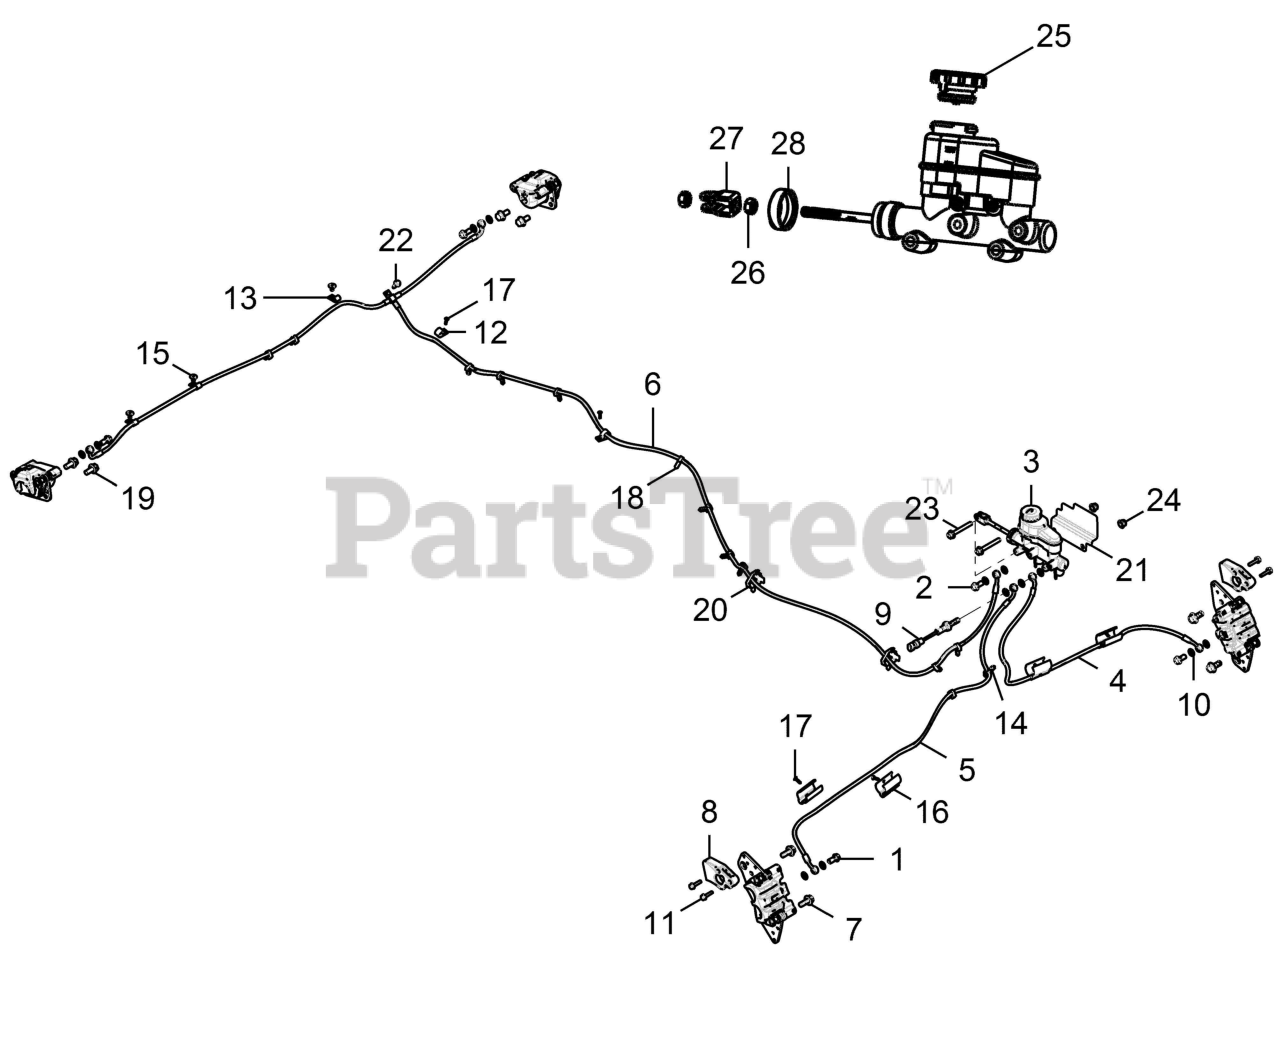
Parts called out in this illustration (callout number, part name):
1	BOLT-BANJO,10MMX1.00
2	BOLT-BANJO, 10MM X 1.25-6G
3	ASM-M/C-T,HBII,STD PUSH ROD
4	LINE-BRAKE,FRONT,LEFT,BRD
5	LINE-BRAKE,FRONT,RIGHT,BRD
6	LINE-BRK,3WAY,123",20B,90B,90B
7	BOLT-M10X1.25X25,HXFLG,W/PATCH
8	SCRAPER, FRONT BRAKE
10	SEAL-STAT-O-3/8,70EP
11	SCR-HXFL,M6X1.0X35 W/PATCHLOCK
12	CLAMP, CABLE
13	CLAMP,HOSE
14	CLIP-ROUTING
15	RIVET(50) *
16	RETAINER-BRAKE LINE,1"
17	POP RIVET(50)
19	BOLT-M10X1.25X20,HXFLG-OLV D
20	CLIP-ROUTING
21	SHIELD-MASTER CYL
22	SCR-M6X1.0X20,HXHD,FLG,TDFM,BL
23	SCR-HXFL-M8X1.25X60 8.8 ZOD
24	NUT-M8X1.25,FLG,NYLOC-OLIVE D
25	RESERVOIR CAP ASM.
26	NUT, HEX
28	DUST BOOT
